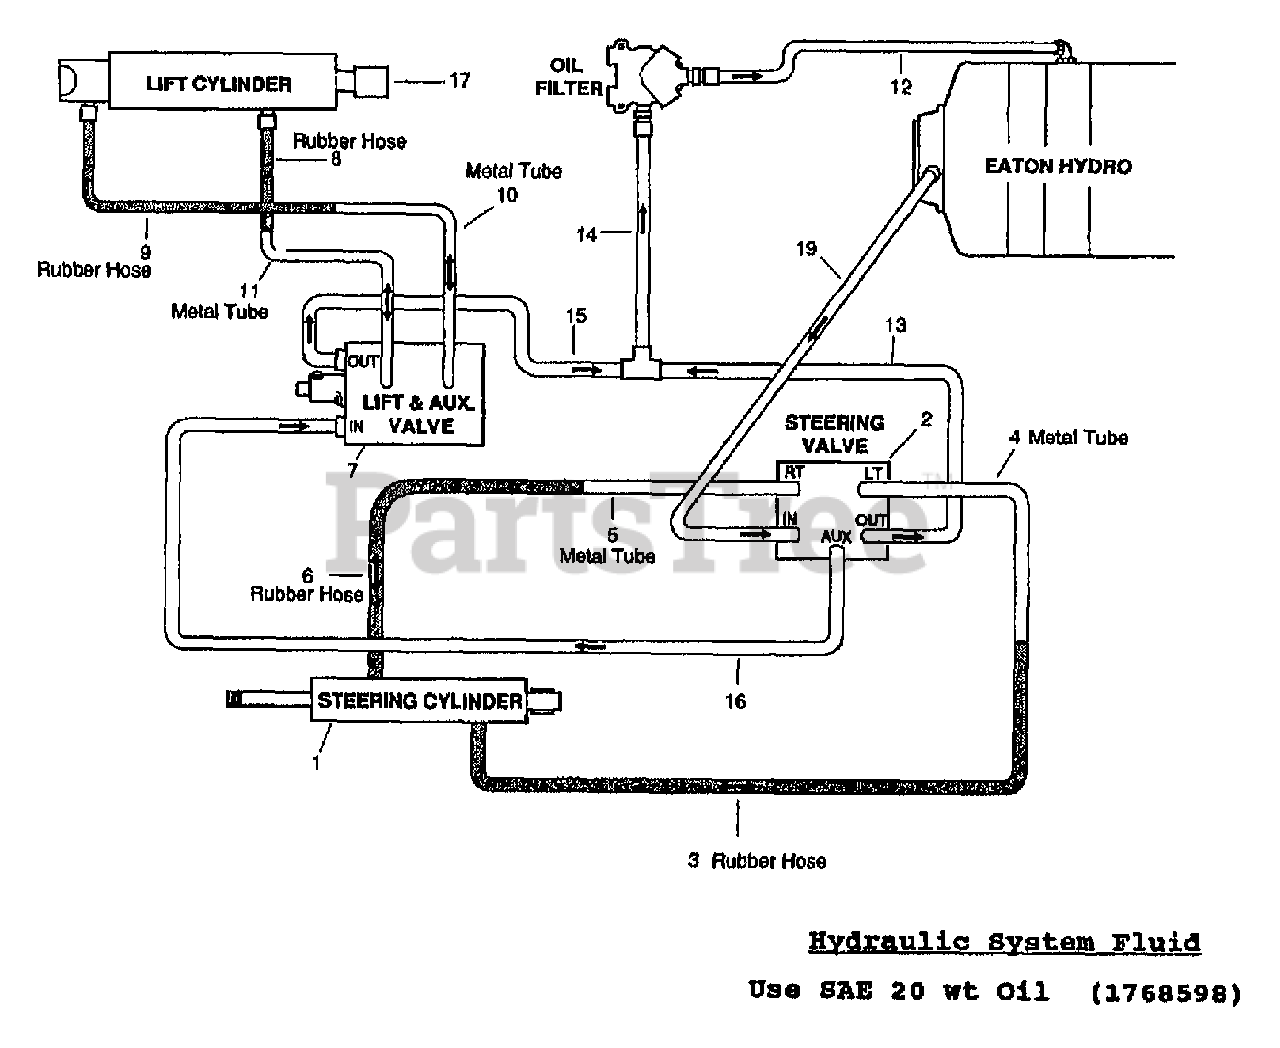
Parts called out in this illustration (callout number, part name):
1	CYLINDER-HYDRAULIC
2	KIT-STEERING VALVE
3	ASSM-HOSE
4	ASSM-TUBE
5	ASSM-TUBE
6	ASSM-HOSE
7	VALVE-LIFT & AUX.
8	ASSM-HOSE
9	ASSM-HOSE
10	ASSM-TUBE
11	ASSM-TUBE
12	ASSM-RETURN TUBE
13	ASSM-TUBE
14	ASSM-TUBE
15	ASSM-TUBE
16	ASSM-TUBE
17	ASSM-CYL HYDRAULIC
19	ASSM-TUBE
